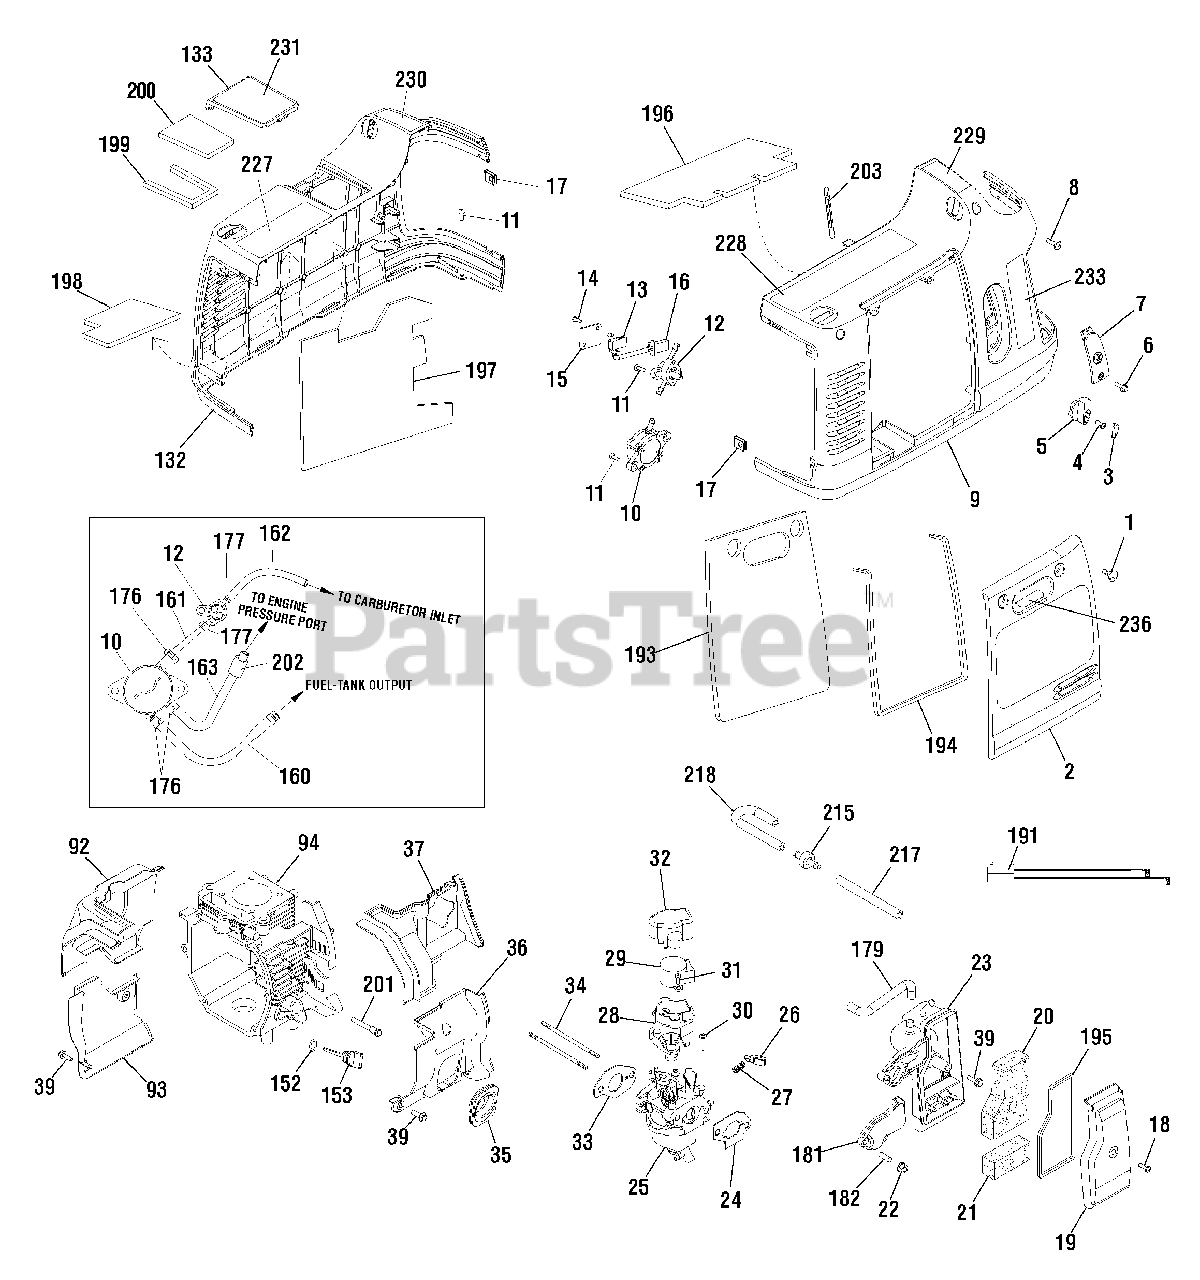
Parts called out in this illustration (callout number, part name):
2	PANEL-ACCESS
4	BOLT
9	COVER-SIDE
11	SCREW
14	BOLT
15	COVER-SWITCH
16	CONNECTION
17	NUT
19	COVER-AIR CLEANER
20	FILTER-A/C FOAM
21	FILTER-A/C FOAM
22	NUT
23	BASE-AIR CLEANER
24	GASKET-AIR CLEANER
27	SPRING
30	BOLT
31	BOLT
35	SEAL-RUBBER
36	DEFLECTOR
37	DEFLECTOR
92	DEFLECTOR
93	DEFLECTOR
94	CRANKCASE
132	COVER-SIDE
133	COVER-SPARK PLUG
176	CLAMP
177	CLAMP
181	COVER-AIR CLEANER
182	SLEEVE
193	FOAM
194	SEAL
195	SEAL
196	FOAM
197	FOAM
198	FOAM
199	SEAL
200	FOAM
201	CYLINDER-BREATHER TUBE
202	TUBE
203	BRACKET
